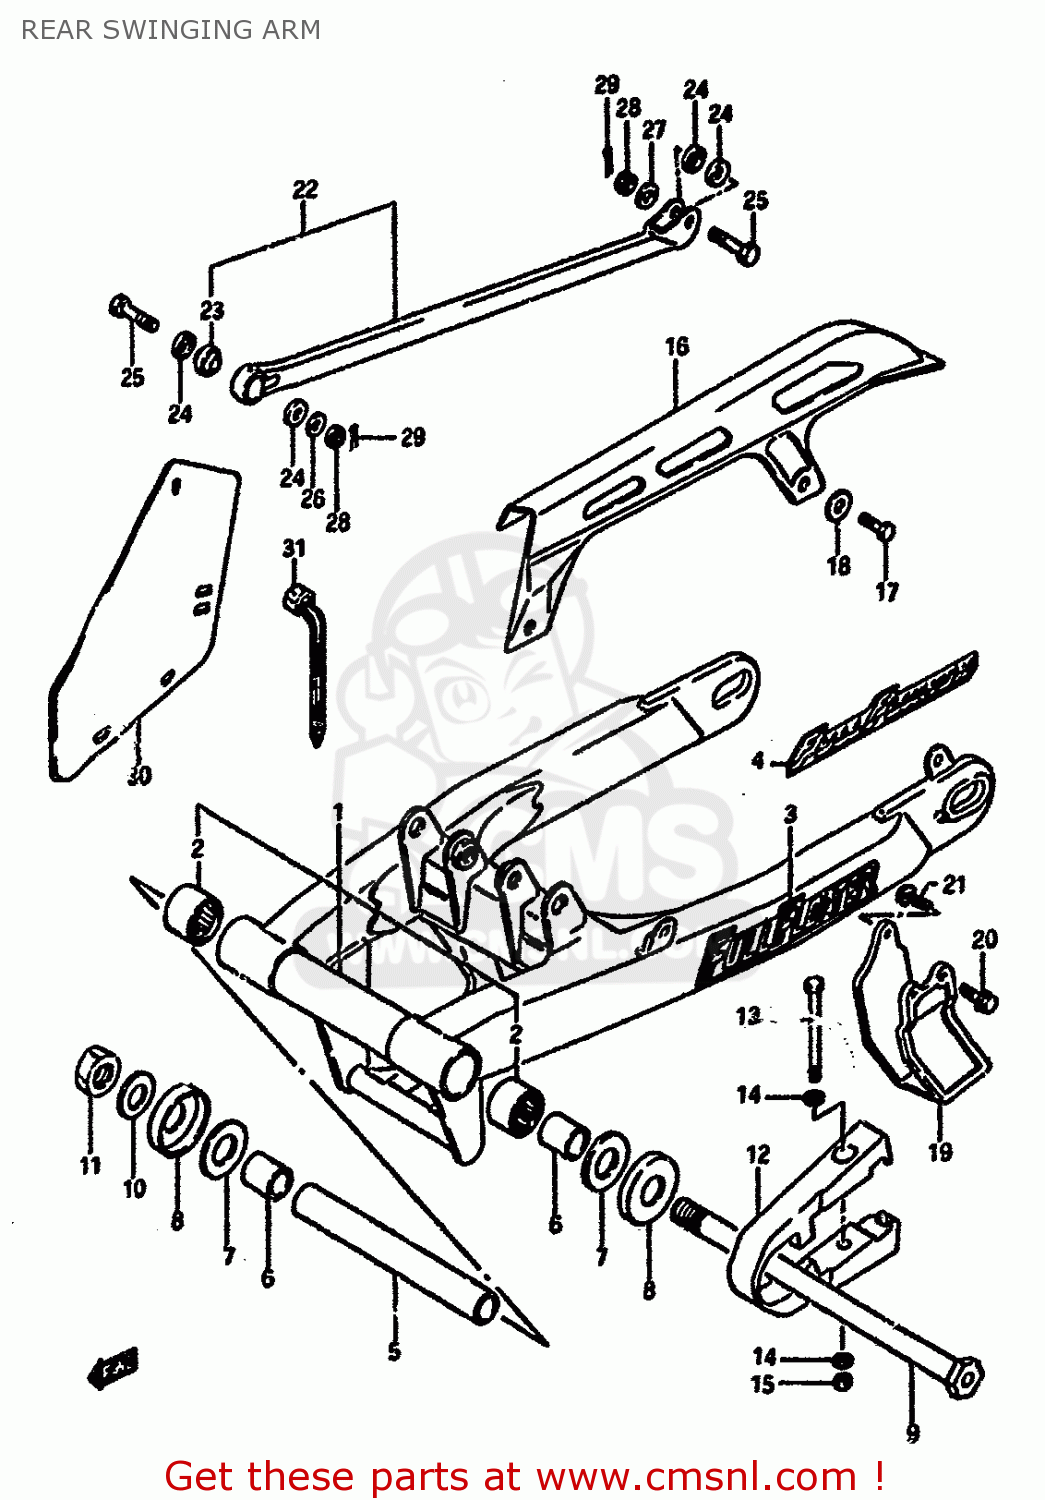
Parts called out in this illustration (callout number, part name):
1	SWINGING ARM ASSY, REAR
2	BEARING(22X29X20)
3	EMBLEM,SWING ARM
4	EMBLEM
5	SPACER,RR SWGARM PIVOT CTR
6	SPACER,RR SWGARM PIVOT
7	WASHER
8	SEAL,RR SWGARM PIVOT DUST
9	SHAFT,RR SWINGINGARM PIVOT
10	WASHER
11	NUT 16MM
12	BUFFER,CHAIN TOUCH DEFENSE
13	BOLT,TOUCH DEFENSE FTG
14	WASHER(5.2X16X1)
15	NUT
16	CASE,CHAIN
17	BOLT
18	WASHER
19	GUIDE,CHAIN
20	BOLT
21	BOLT 6X16
22	LINK,REAR TORQUE
23	SPHERICAL BEARING,TORQUE
24	25-1
25	BOLT 8X32
26	WASHER,FRONT
27	WASHER
28	NUT 8MM
29	PIN 20X20
30	GUARD, CHAIN
31	CLAMP(L:125)
